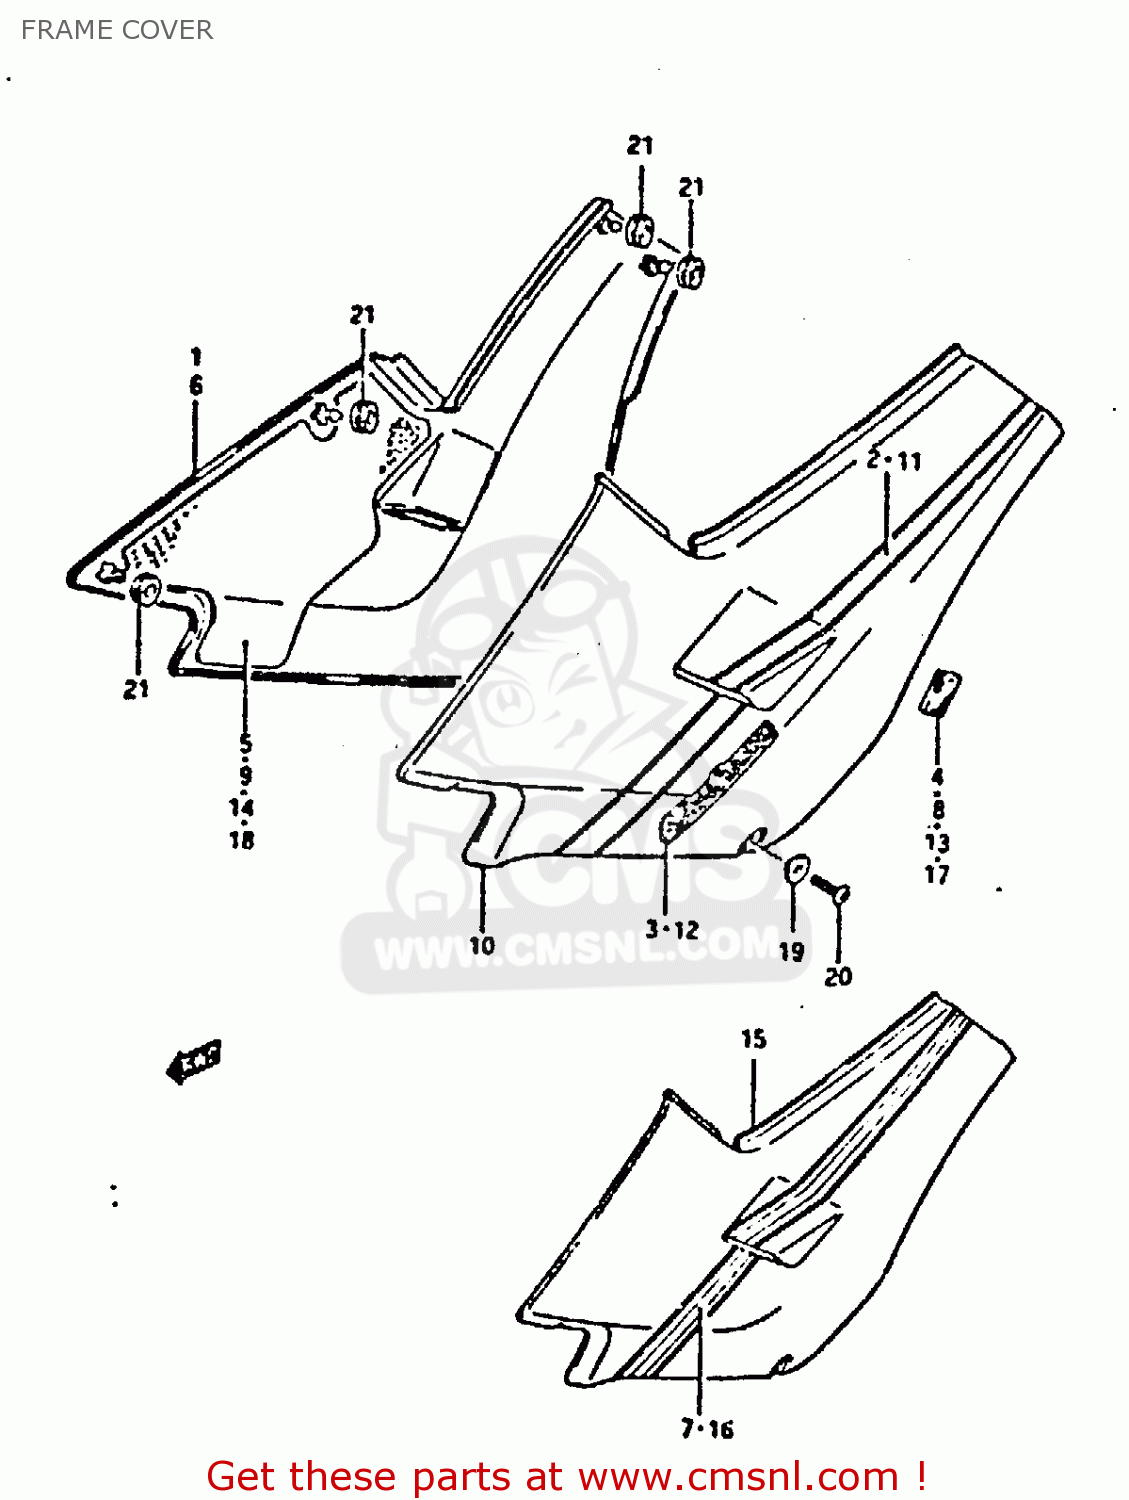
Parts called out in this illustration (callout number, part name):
1	FRAMEDEKSEL
4	CUSHION,FR FENDER
6	FRAMEDEKSEL
8	CUSHION,FR FENDER
10	COVER.FRAME LH
13	CUSHION,FR FENDER
15	COVER.FRAME LH
17	CUSHION,FR FENDER
19	WASHER
20	SCREW
21	CUSHION,COVER HEAD
